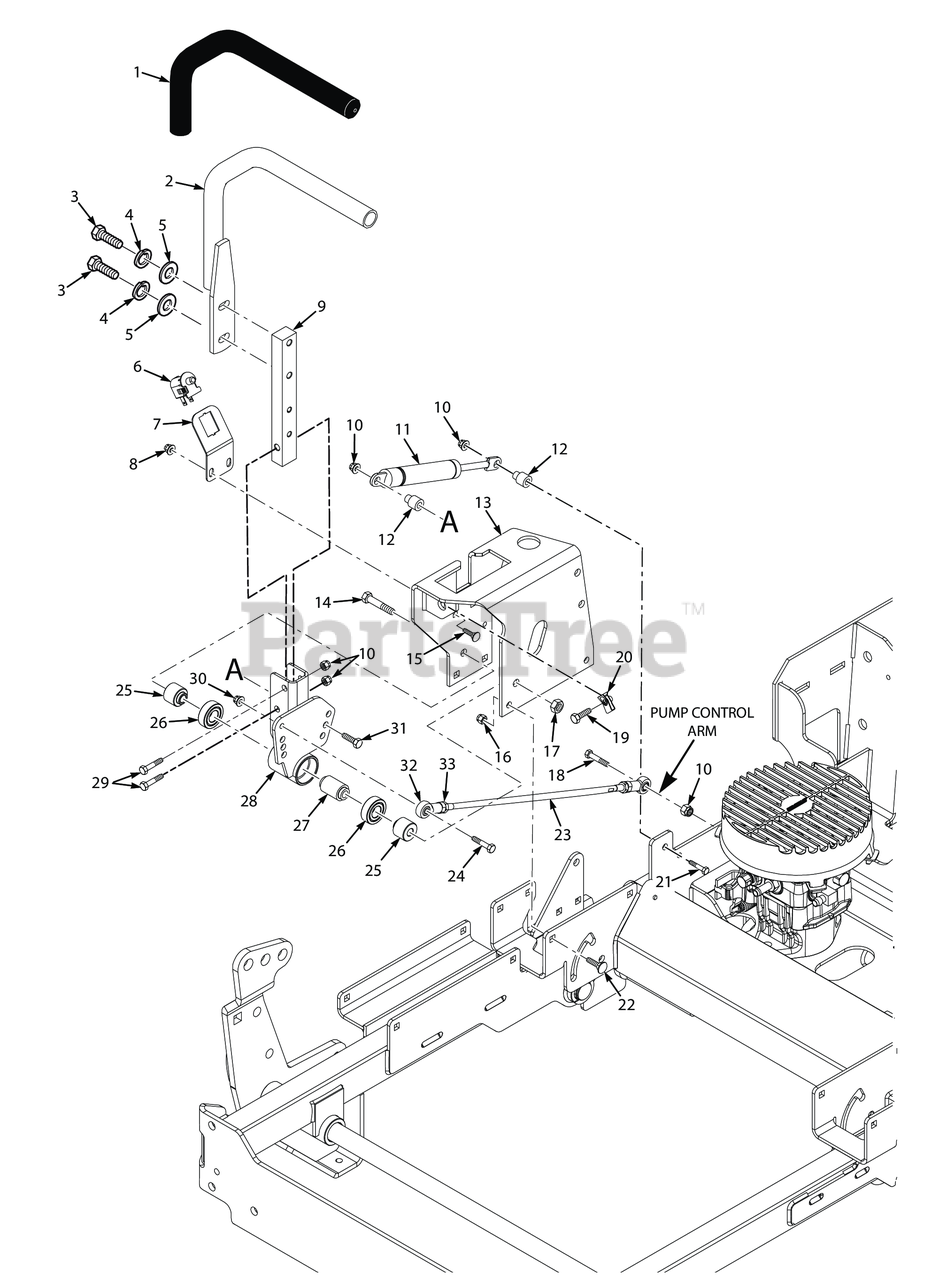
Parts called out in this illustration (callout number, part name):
1	Grip, Control Handle
2	Handle Bar w/Grip
3	Bolt, Hex Head 3/8-16 x 1-1/4", Kawasaki FX / FS
4	Lockwasher, 3/8" Spring, Kawasaki FX / FS
5	Flatwasher, 3/8" Special (.391 x .938 x .105)
6	Switch, Interlock, Normally Open
7	Bracket, Operator Presence Switch
8	Nut, Flanged Elastic Stop 1/4-20
9	Bar, Control Lever
10	HEX NUT, ELASTIC STOP LOCK, 5/16-18
11	Gas Damper
12	Spacer, Pump Dampener
13	Control Plate w/decal
14	Bolt, Hex Head 3/8-16 x 4-1/4"
15	Serr. Fl. Hex Head CPSCR, 1/4-20 x 3/4"
16	Nut, Serrated Flange 5/16-18 (Right Front Engine Mounting, Briggs and Kohler Only)
17	Bolt, Hex Head 3/8-16 x 1" Ser. Flg.
18	Bolt, Heax Head 5/16-18 x 1" (48V / 52V)
19	Bolt, Hex Head 3/8-16 x 1-1/4" with Thread Lock Patch
20	U-Nut, 3/8-16 (short)
21	Bolt, Hex Head 5/16-18 x 1-1/2" (Right Front Engine Mounting, Briggs and Kohler Only)
21	Bolt, Hex Head 5/16-18 x 1-1/2" - Front
22	Bolt, 5/16-18 x .75 RHSN Carriage
23	Linkage Assy, Steering
23	Rod End, 5/16-24 LH
23	Nut, Jam 5/16-24 UNF-2B
24	Bolt, Hex Head, 1/4-20 x 1-1/2"
25	Spacer, Controls
26	BEARINGS, BALL, NEUTRAL RETURN
27	Spacer, Bearing
28	Pivot Weldment, Control Arm RH
28	Pivot Weldment, Control Arm LH
29	Bolt, Hex Head 5/16-18 x 1-1/2" - Front
30	HEX, NUT, ELASTIC STOP LOCK, 1/4-20
31	Bolt, Hex Head 5/16-18 x 1-1/2" (Right Front Engine Mounting, Briggs and Kohler Only)
32	Rod End, 5/16-24 RH
33	Nut, 5/16-24 UNF Jam LH
